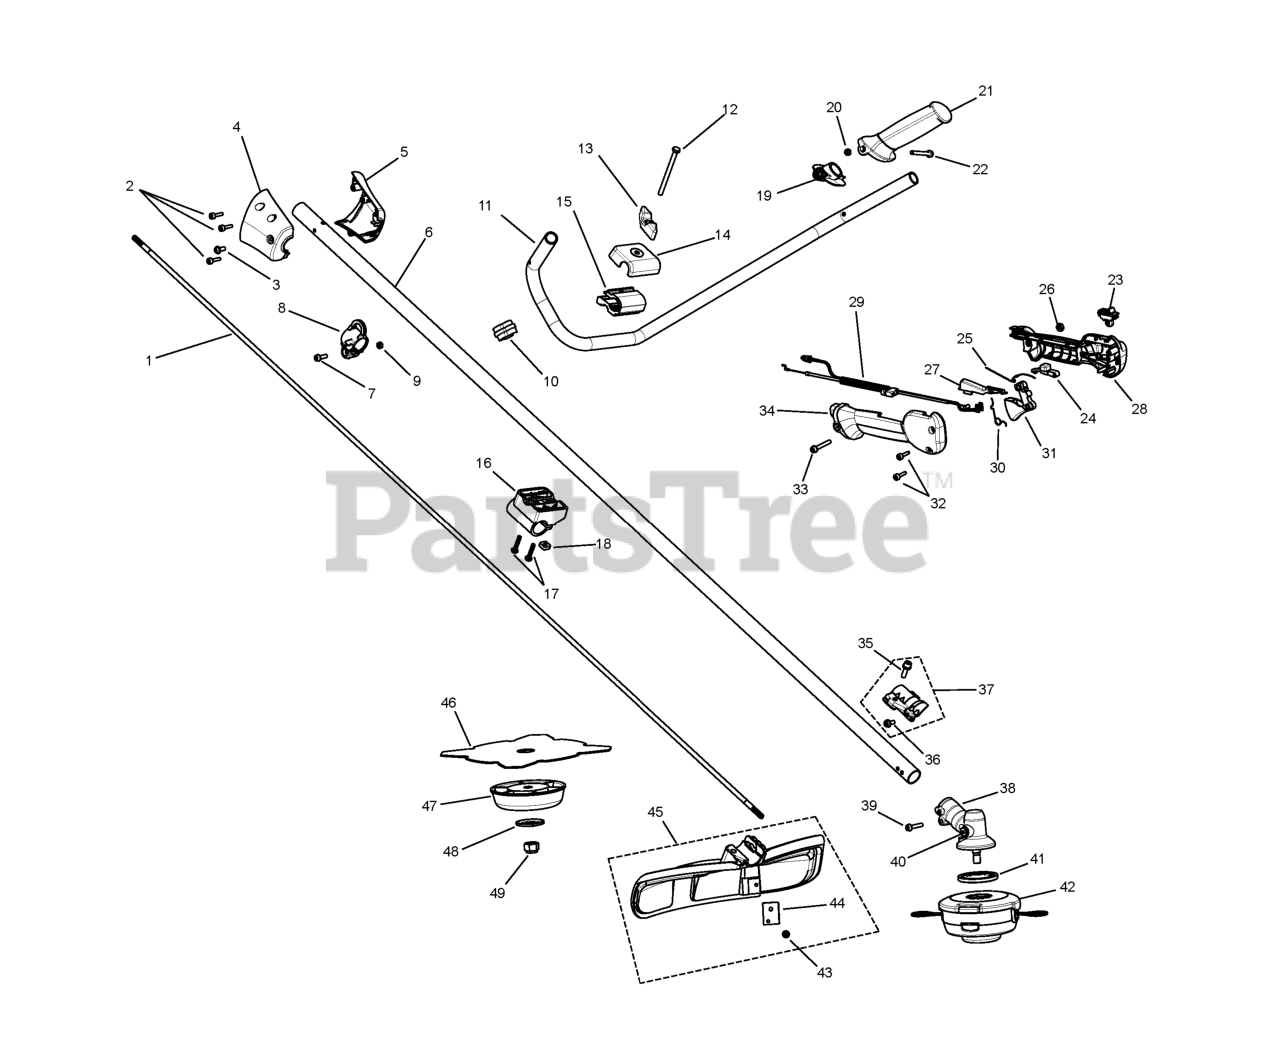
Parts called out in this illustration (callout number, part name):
1	DRIVESHAFT 525L
2	SCREW
3	SCREW
4	CONE
5	CONE NOSE BULLHORN L/H HUSQ OR
6	KIT SVC 325R DRIVESHAFT EU
6	KIT SVC 325R DRIVESHAFT RUS/LA
7	SCREW
8	HARNESS HOLDER
9	NUT
10	GROMMET
11	HANDLE
12	SCREW
13	HANDLE
14	BRACKET
15	HOLDER
16	HOLDER
17	SCREW
18	NUT
19	BRACKET
20	NUT
21	HANDLE
22	SCREW ITXSCFM M5X45 T27 12.9
23	STOP BUTTON
24	STARTER THROTTLE LOCK
25	SPRING
26	NUT
27	THROTTLE LOCKOUT
28	HANDLE HALF LEFT
29	CABLE ASSY
30	SPRING
31	THROTTLE CONTROL
32	SCREW
33	SCREW IHSCFM
34	HANDLE
35	BOLT
36	BOLT
37	ASSY CLAMP 523L
38	GEARHEAD
39	SCREW
40	PLUG
41	DRIVE DISC
42	TRIMMER HEADS
43	SCREW ITXSCFT PW4.8X16 T27 CH
44	LINE CUTTER
45	COMBINATION GUARD
46	Blade - Grass
47	SUPPORTING CUP
48	SUPPORT FLANGE
49	GEARHEAD NUT - BRUSHCUTTER
